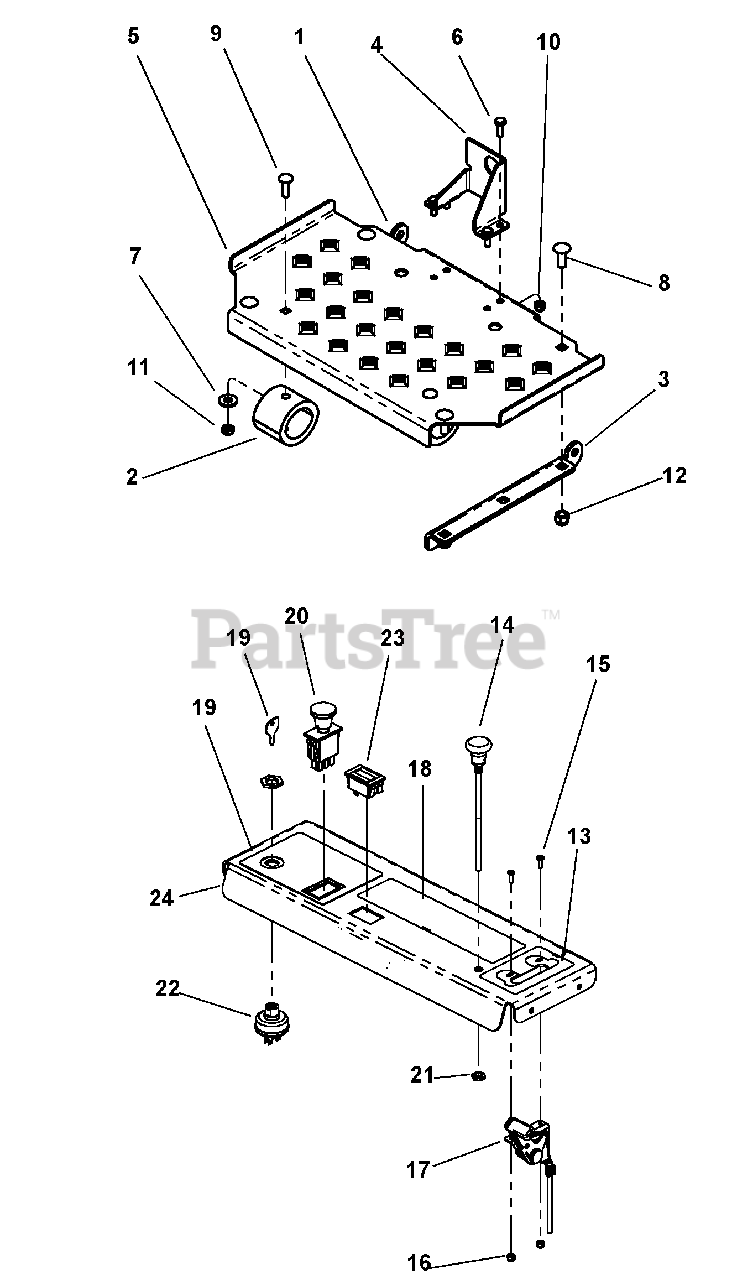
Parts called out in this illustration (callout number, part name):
1	Plate, Platform Tab LH
2	Bumper, Miner GBR-6
3	Plate, Platform Tab Left Hand
4	Anchor, Operator Presence Control
5	Platform
6	Bolt, Hex .25-20 x .75 Grade 5
7	Washer, Flat-Steel .38 x .875 x .083
8	Bolt, Round Head Square Neck .38-16 x 1.00 Grade 5
9	Bolt, Round Head Square Neck .31-18 x 1.00 Grade 5
10	Nut, Locking-Nylon .250-20
11	Nut, Locking-Nylon .312-18
12	Nut, Locking-Nylon .38-16
13	Decal, Throttle
14	Cable, Choke
15	Screw, 8-32 x .50 Pan PHL Y
16	Nut, 8-32 Elastic Stop
17	Cable, Throttle
18	Decal, General Caution
19	Decal, PTO & Key Switch
20	Switch, PTO Engagement
21	Nut, Hex .38-16
22	Switch, Key - 3 Position
23	Meter, Hour Digital
24	Top, Console
